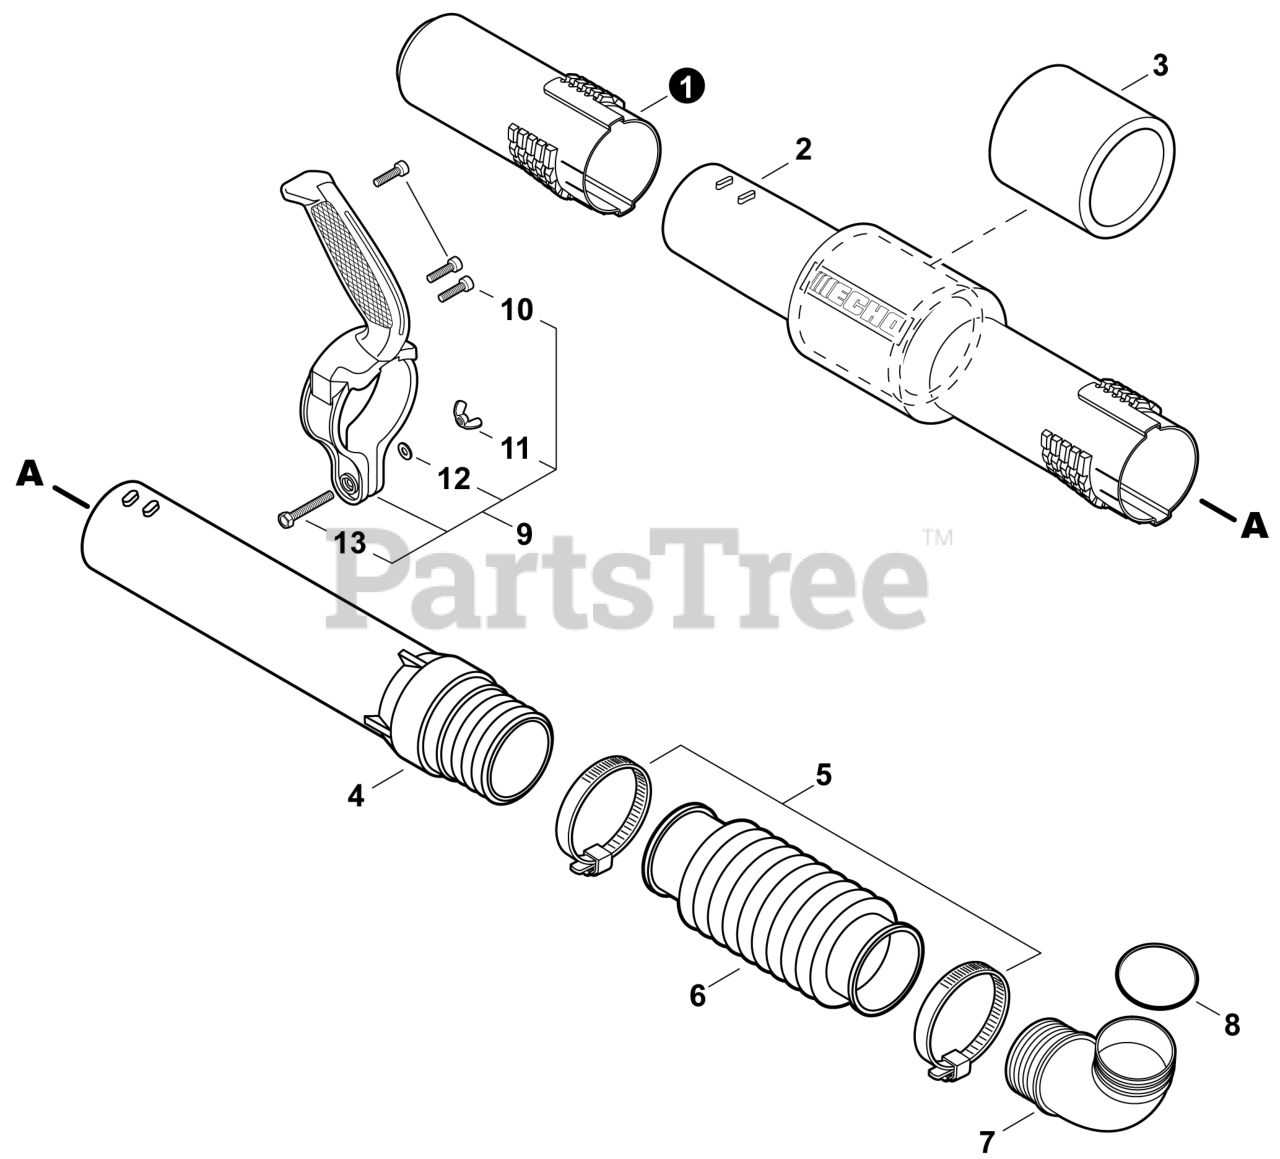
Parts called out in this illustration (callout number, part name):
1	TUBE, BLOWER - NOZZLE
2	TUBE, BLOWER - STRAIGHT
3	PAD, FOAM
4	TUBE, BLOWER - SWIVEL
5	CLAMP - BAND 78 MM / 103 MM
6	TUBE, BLOWER - FLEXIBLE
7	TUBE, BLOWER - ELBOW
9	HANDLE KIT - BLOWER TUBE
10	BOLT, TORX 4x16
11	NUT, WING 6
12	WASHER 6.5x11.5x0.8
13	BOLT 6x25
